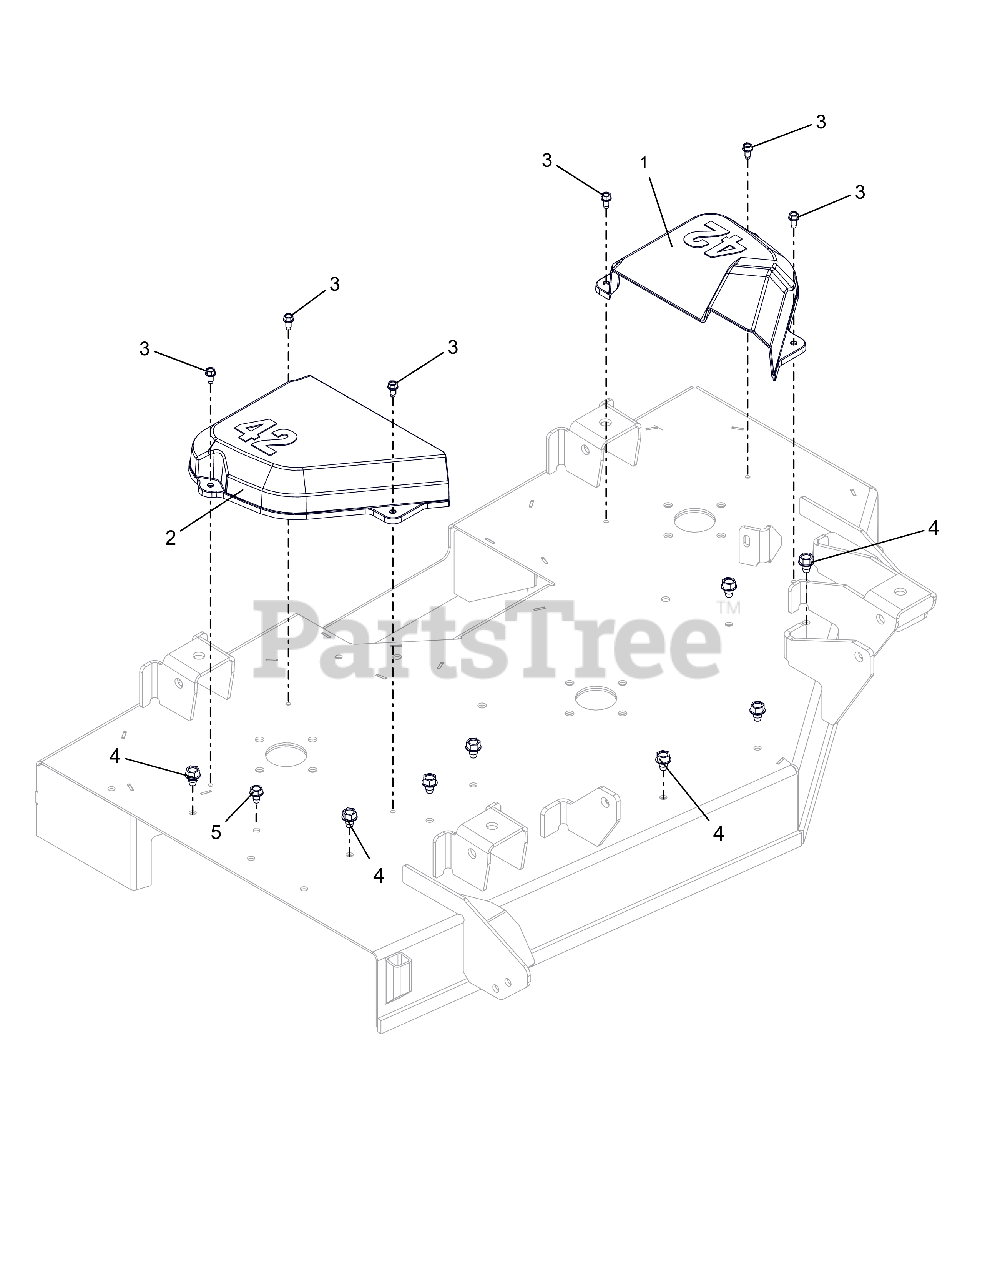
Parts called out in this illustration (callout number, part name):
1	COVER, BELT 42" LH
2	COVER, BELT 42" RH
3	SCR-TAP .25-20X.50 HWH ZCC
4	SCR,TAP .375-16X.50 HWH TR ZCC
5	@SCR-TAP .31-18X.50 HWH TR YWZ
